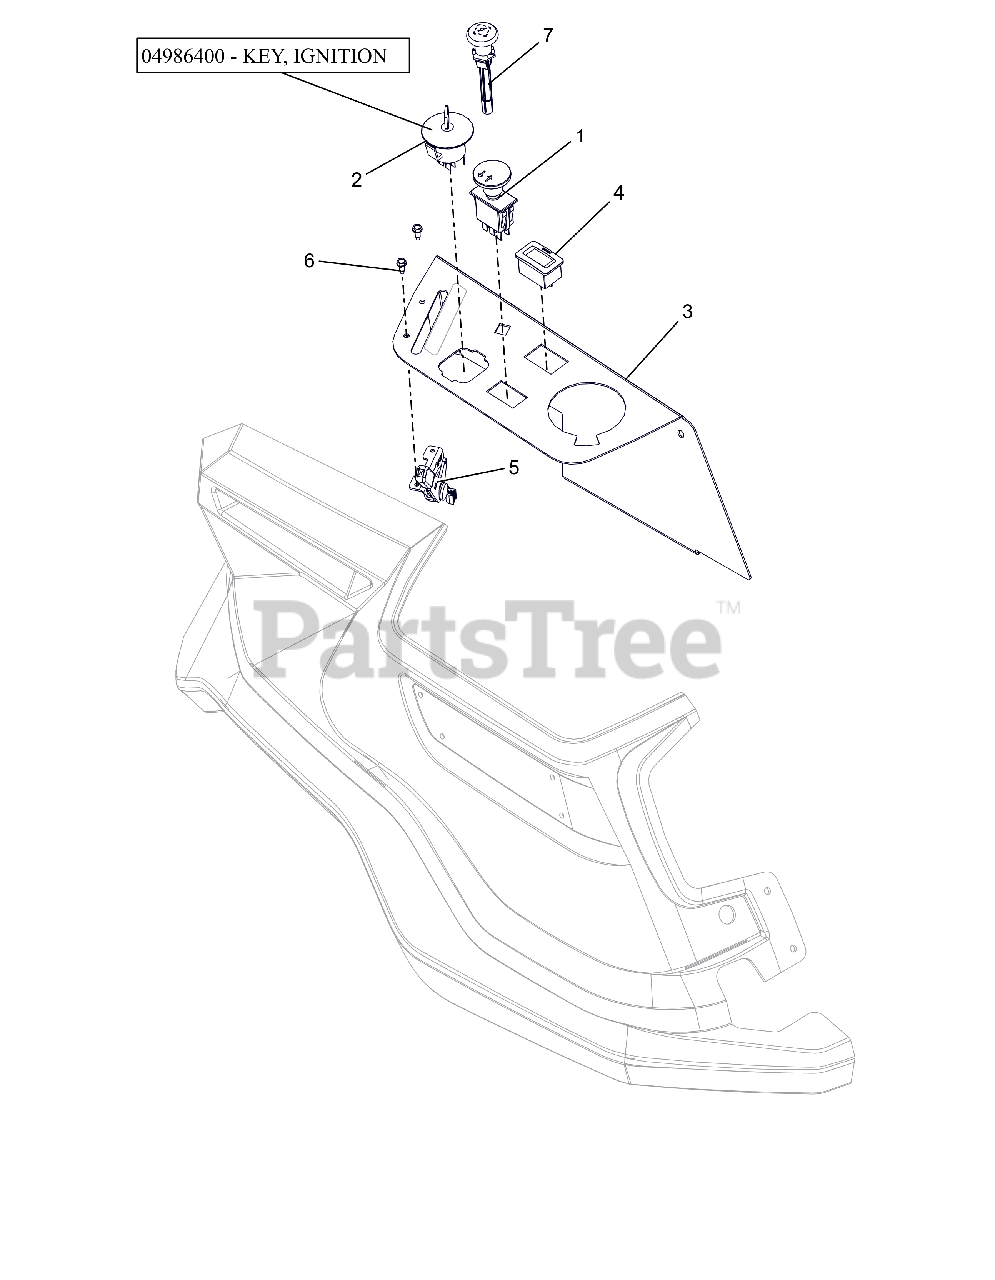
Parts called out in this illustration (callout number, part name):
1	SWITCH, CLUTCH (YELLOW)
2	KEYSWITCH-IGNITION 4 POS
2	KEY, IGNITION
3	PANEL, RIGHT SIDE FENDER MOUNT
4	HOUR METER
5	CABLE - THROTTLE CONTROL
6	@SCR-TAP 10-24X.50 HWH TR YWZC
7	CABLE - CHOKE, SNAP-IN
